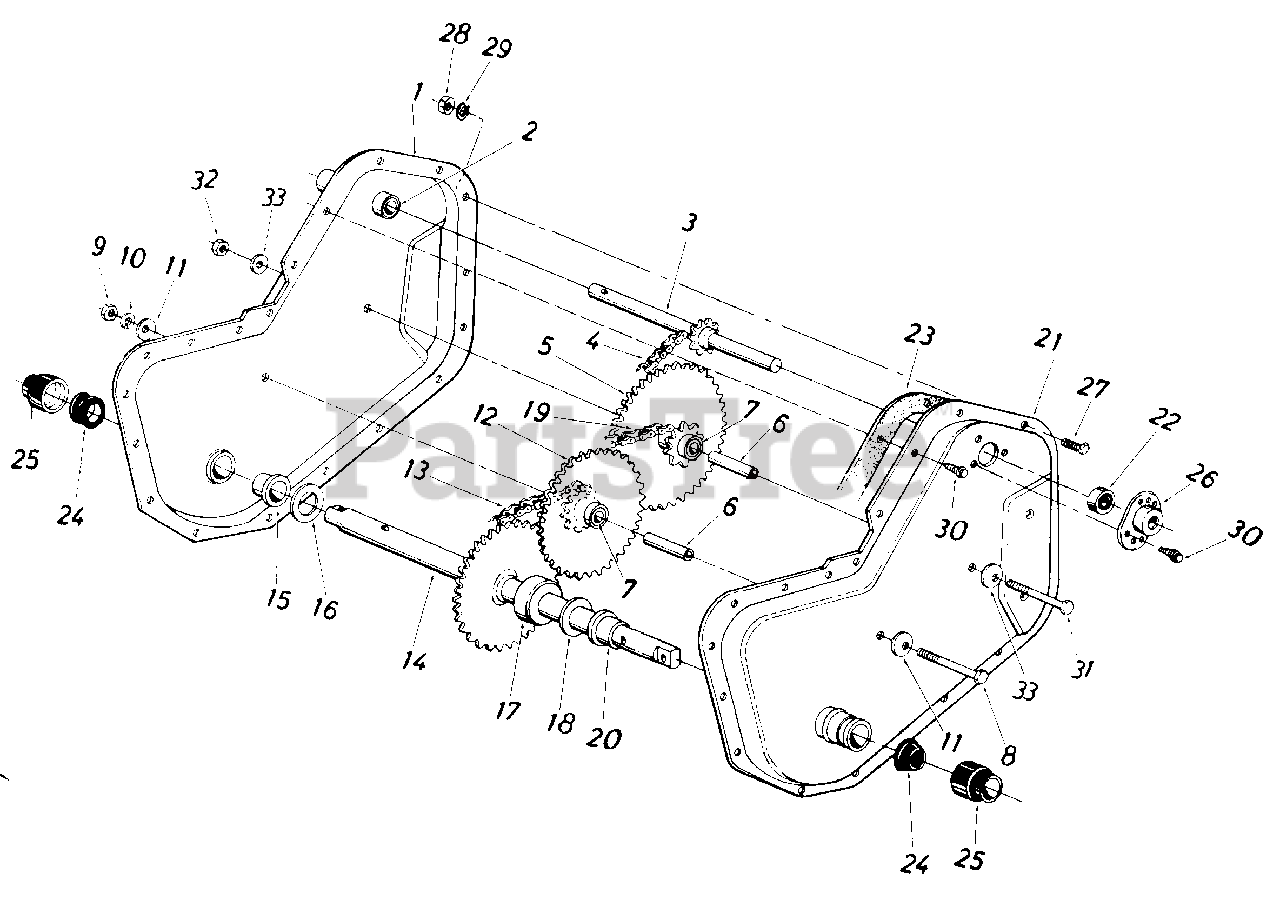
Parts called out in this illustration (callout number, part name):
1	Chain Case Half Ass'y.-R.H.
2	Bearing 5/8" I.D. x .813" O.D. x 1.31" Lg.
3	Input Shaft Ass'y.
4	Chain #35-3/8" Pitch x 44 Links
5	Sprocket and Hub Ass'y.
6	Bearing Inner Axle
7	Sleeve Brg. 5/8" I.D. x 3/4" O.D. x 1.50
8	Hex Bolt 3/8-24 x 2.50" Lg.
9	Hex Ins. L-Nut 3/8-24 Thd.
10	L-Wash. 3/8" I.D.
11	Bell-Wash. .41" I.D. x 1.13" O.D. x .03
12	Sprocket & Hub Ass'y. 9T-22T
13	#420 Chain 1/2 Pitch x 28 Links Endless
14	Wheel Shaft Ass'y.
15	Flange Bearing
16	Fl-Wash. .88" I.D. x 1.5" O.D. x .03
17	Spacer 7/8" I.D. x 13/4" O.D. x.68" Lg.
18	Fl-Wash. .88" I.D. x 1.50" O.D. x .03
19	#420 Chain 1/2" Pitch x 30 Links Endless
20	Flange Bearing
23	Gasket
26	Bearing Housing
27	Hex Bolt 1/4-28 x 5/8" Lg.
28	Hex Nut 1/4-28 Thd.
29	L-Wash. 1/4" I.D.
30	Hex Wash. S-Tap Scr. 1/4-20 x.50" Lg.
31	Hex Bolt 5/16-18 x 2.5" Lg.
32	Hex Cent. L-Nut 5/16-18 Thd.
33	Fl.-Wash. 5/16" I.D.
